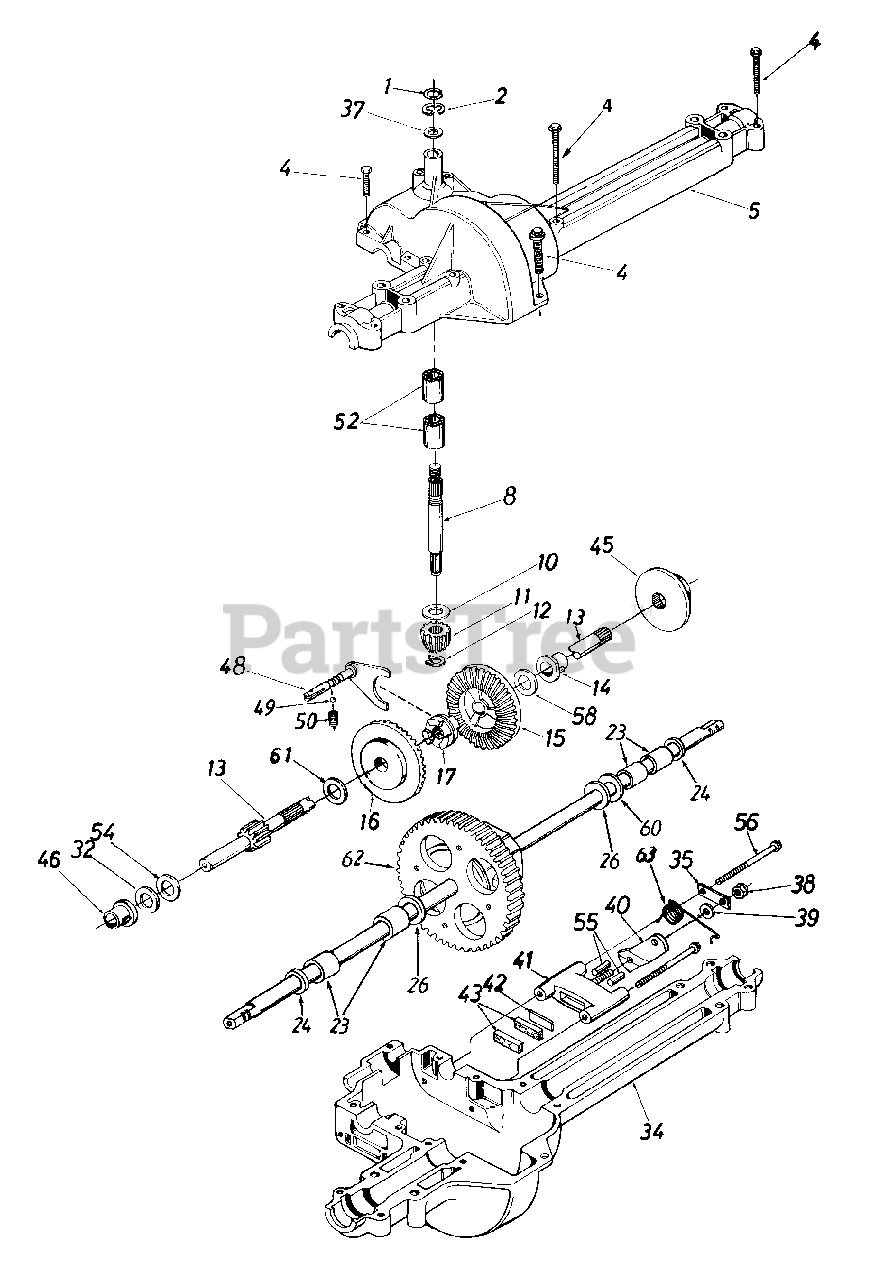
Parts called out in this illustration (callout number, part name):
1	Wire Ring
2	"E"-Ring
4	Hex Tap Scr. 1/4-20 x 1.625 Lg.
5	Upper Housing
8	Input Shaft
10	Thrust Washer 5/8" I.D. x 1.25" O.D.
11	Pinion Input 14T
12	Retaining Ring
13	Drive Shaft-R.H. Brake
14	Flange Brg. 5/8" I.D. x 3/4" Lg.
15	Bevel Gear 42T Small I.D.
16	Bevel Gear 42T Large I.D.
17	Clutch Collar
23	Sleeve Bearing 3/4" I.D. x 1.0" Lg.
24	Oil Seal 3/4" I.D.
26	Fl-Wash. .760" I.D. x 1.5" O.D.
32	Washer
34	Lower Housing
35	Anti-Rotation Brkt.
37	Washer
38	Hex Nut 5/16-24 Thd.
39	Fl-Wash. .344" I.D. x .875" O.D.
40	Actuating Arm
41	Brake Yoke
42	Puck Plate
43	Brake Puck
45	Brake Disc
46	Flange Bearing 5/8" I.D. x 15/16" Lg.
48	Shift Fork Ass'y.
49	Ball Detent .250" Dia.
50	Spring Detent
52	Needle Brg. 5/8" I.D. x 1/2" Lg.
54	Fl-Wash. 5/8" I.D. x 1" O.D.x .020 Thk.
55	Actuating Pin 5/16" Dia.
56	Hex Wash Hd. Self-Tap Scr. 1/4-20
58	Fl-Wash. 5/8" I.D. x 1" O.D. x.020 Thk.
60	Washer
61	Thrust Washer
62	Differential Ass'y.
63	R.H.-Brake Spring
